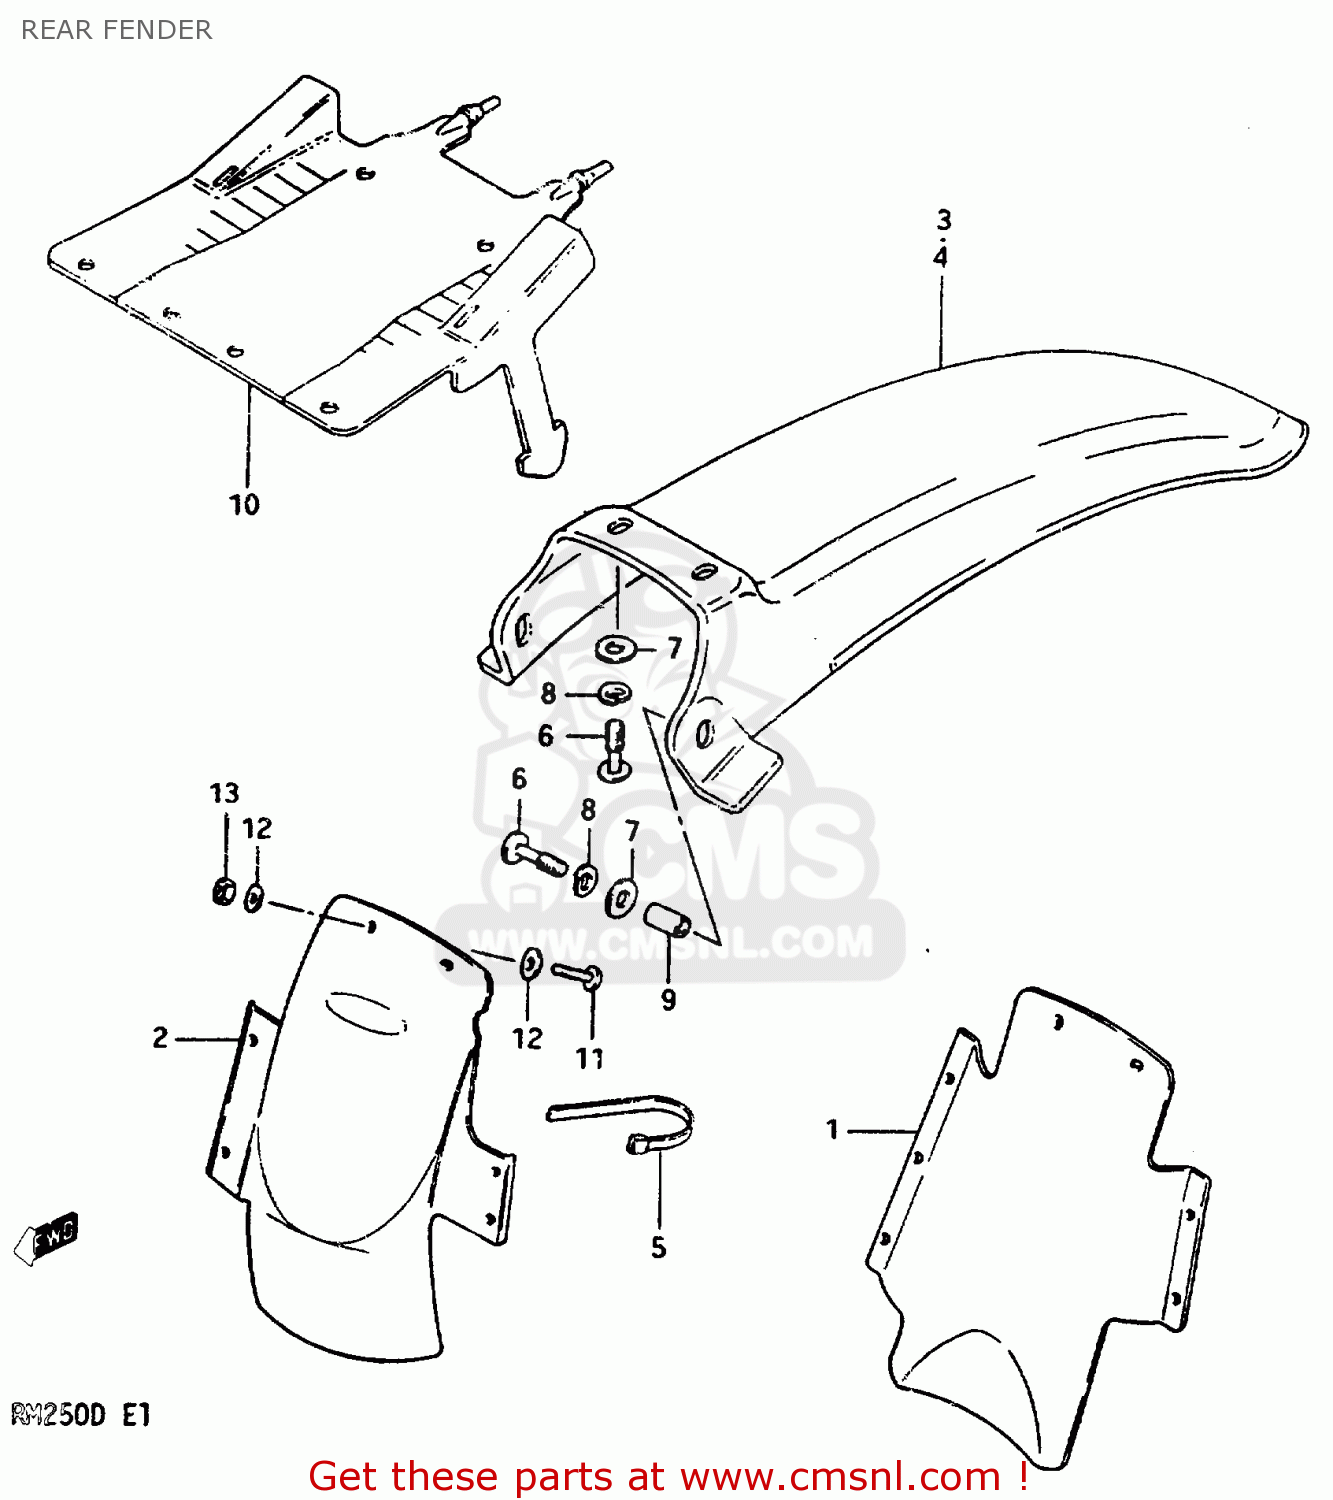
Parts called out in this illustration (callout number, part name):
1	FENDER,REAR
2	REAR FENDER,FRONT
3	FENDER,RR
4	FENDER,RR
5	CLAMP
6	SCREW
7	WASHER (6.5X20X1.2)
8	WASHER,LOCK
9	SPACER
10	GUIDE,RR FENDER MUD
11	SCREW
12	WASHER
13	NUT
